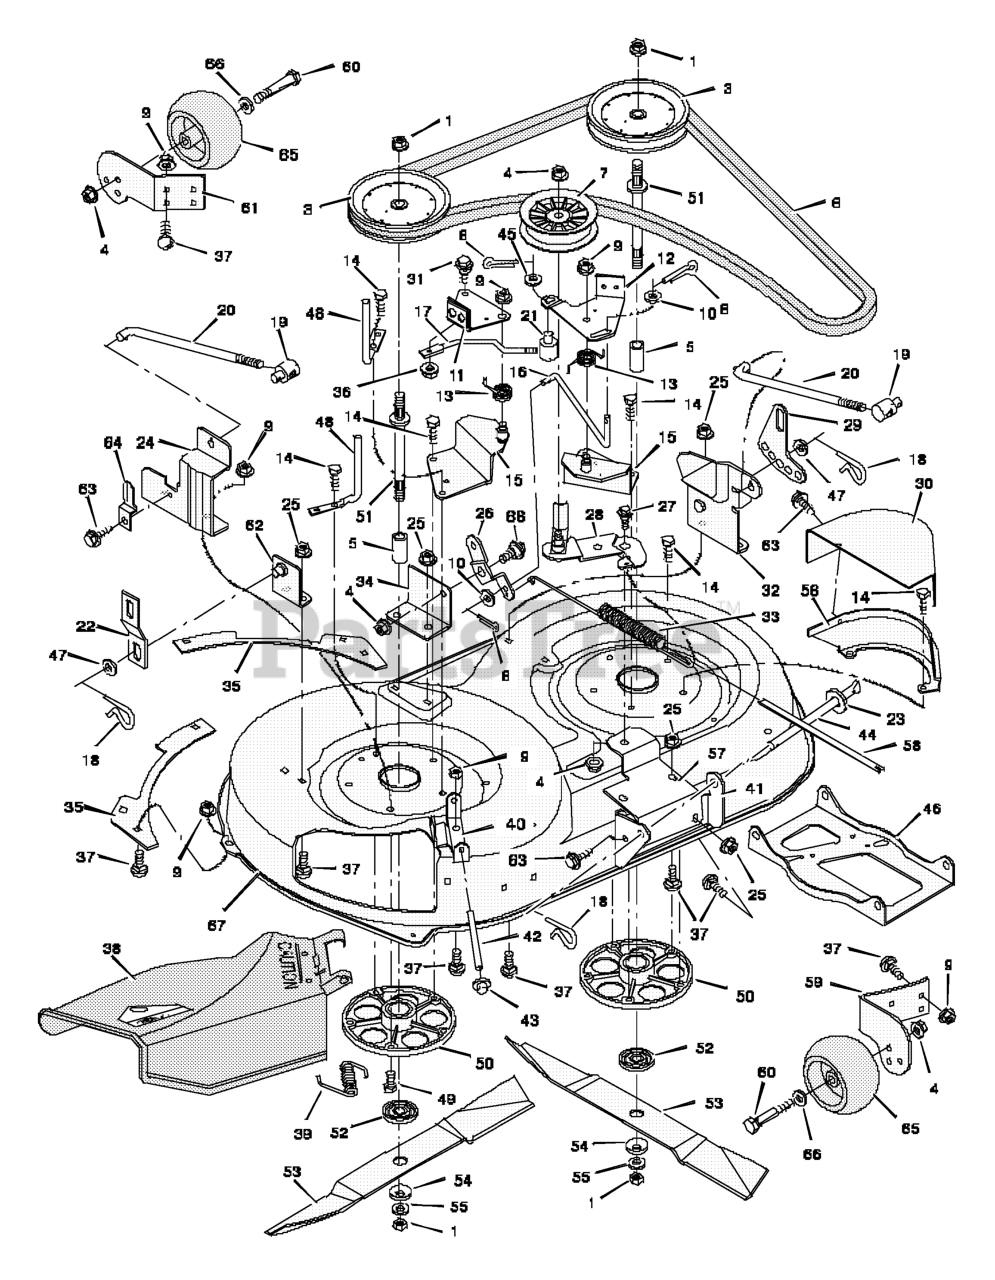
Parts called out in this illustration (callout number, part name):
1	Nut, Hex
3	Pulley, Jackshaft
4	Locknut, Flange
5	Spacer
6	Belt, Blade Drive
7	Pulley, Idler
8	Pin, Cotter
9	Locknut, Flange
10	Washer
11	Brake Assembly, Right
12	Brake Assembly, Left
13	Spring, Torsion
14	Bolt, Hex
15	Bracket Assembly, Brake
16	Rod, Brake
17	Rod, Cross Link
18	Pin, Hair
19	NUT, Adjusting, 1/2-13
20	Rod, Adjuster
21	Nut, Adjustable
24	Bracket, Right
25	Nut, Flange
26	Bracket, Pivot
27	Bolt, Shoulder
28	Arm Assembly, Idler
29	Plate, Adjuster
30	Cover, Pulley
31	Bolt, Shoulder
32	Bracket Assembly, Left Lifter
33	Spring, Extension
34	Bracket, Pivot
36	Locknut, Flange
37	Bolt, Carriage
38	Deflector Assembly, Chute
39	Spring, Torsion
40	Bracket, Hinge
41	Bracket, Front Hanger
42	Rod, Deflector
43	Cap, Push On
44	Rod, Hanger
46	Hanger, Front
48	Rod, Belt Guide
49	Bolt, Hex
50	Housing, Jackshaft
51	Jackshaft
52	Adapter, Blade
53	Blade, 42" (2 required)
54	Washer, Belleville
56	Bracket, Pulley Cover
57	Bracket, Idler Mount
58	Indicator, Plastic
59	Bracket, Right Wheel
60	BOLT, Gauge Wheel
61	Bracket, Left Wheel
62	Bracket Assembly, Right Lifter
64	Guide, Belt
65	Wheel, Gauge
66	Washer
67	Housing, Blade
68	Bolt, Shoulder
